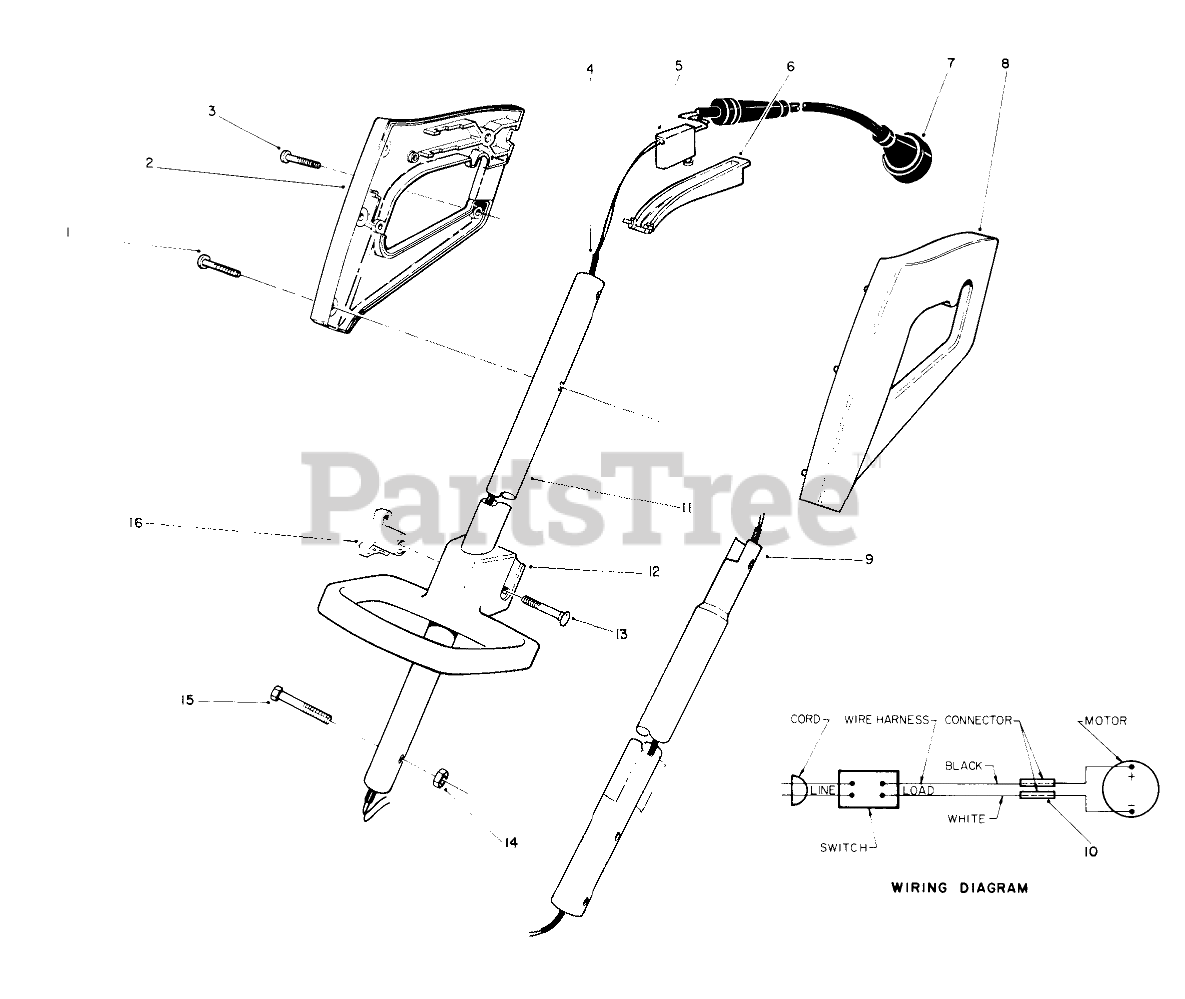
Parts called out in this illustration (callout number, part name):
1	Screw
2	HANDLE GRIP, RH
3	SCREW-PPH
4	WIRE HARNESS
5	SWITCH
6	Bar Switch
7	Cord-Power
8	HANDLE GRIP, LH
9	TUBE-LOWER
10	CONNECTOR WIRE JOINT
11	Tube-Upper
12	Handle-Adjust
13	BOLT-CARR
14	NUT-LOCK, NI
15	HEX HD MACHINE SCREW
16	HANDLE KNOB
